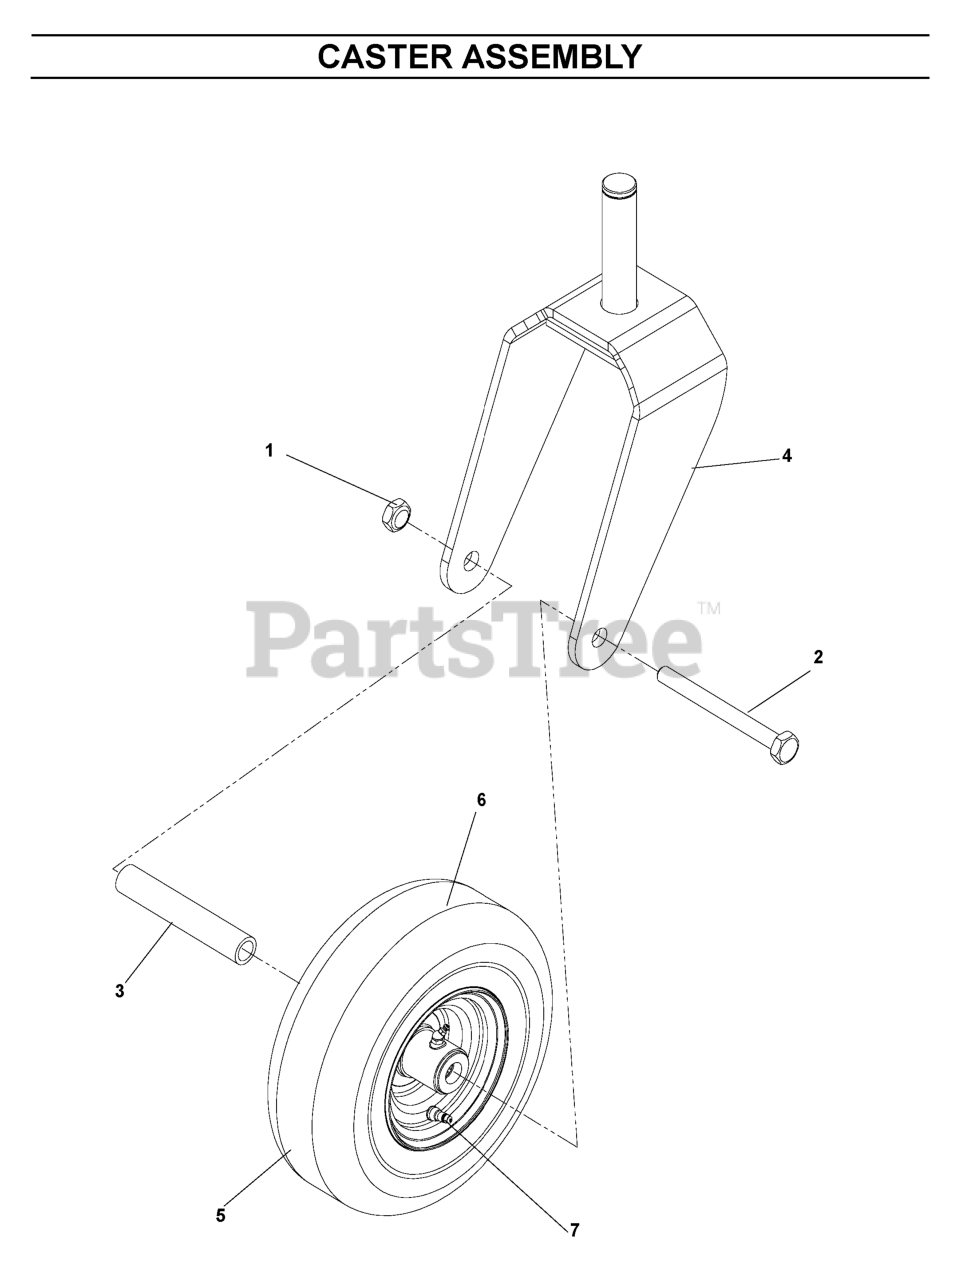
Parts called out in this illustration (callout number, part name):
1	NUT 1/2-13 HEX NYLOC ZD
2	HCS 1/2C X 5 1/2
4	CASTER WLDT
5	TIRE COMPLETE
6	TIRE - CASTER
7	VALVE STEM TR-412
